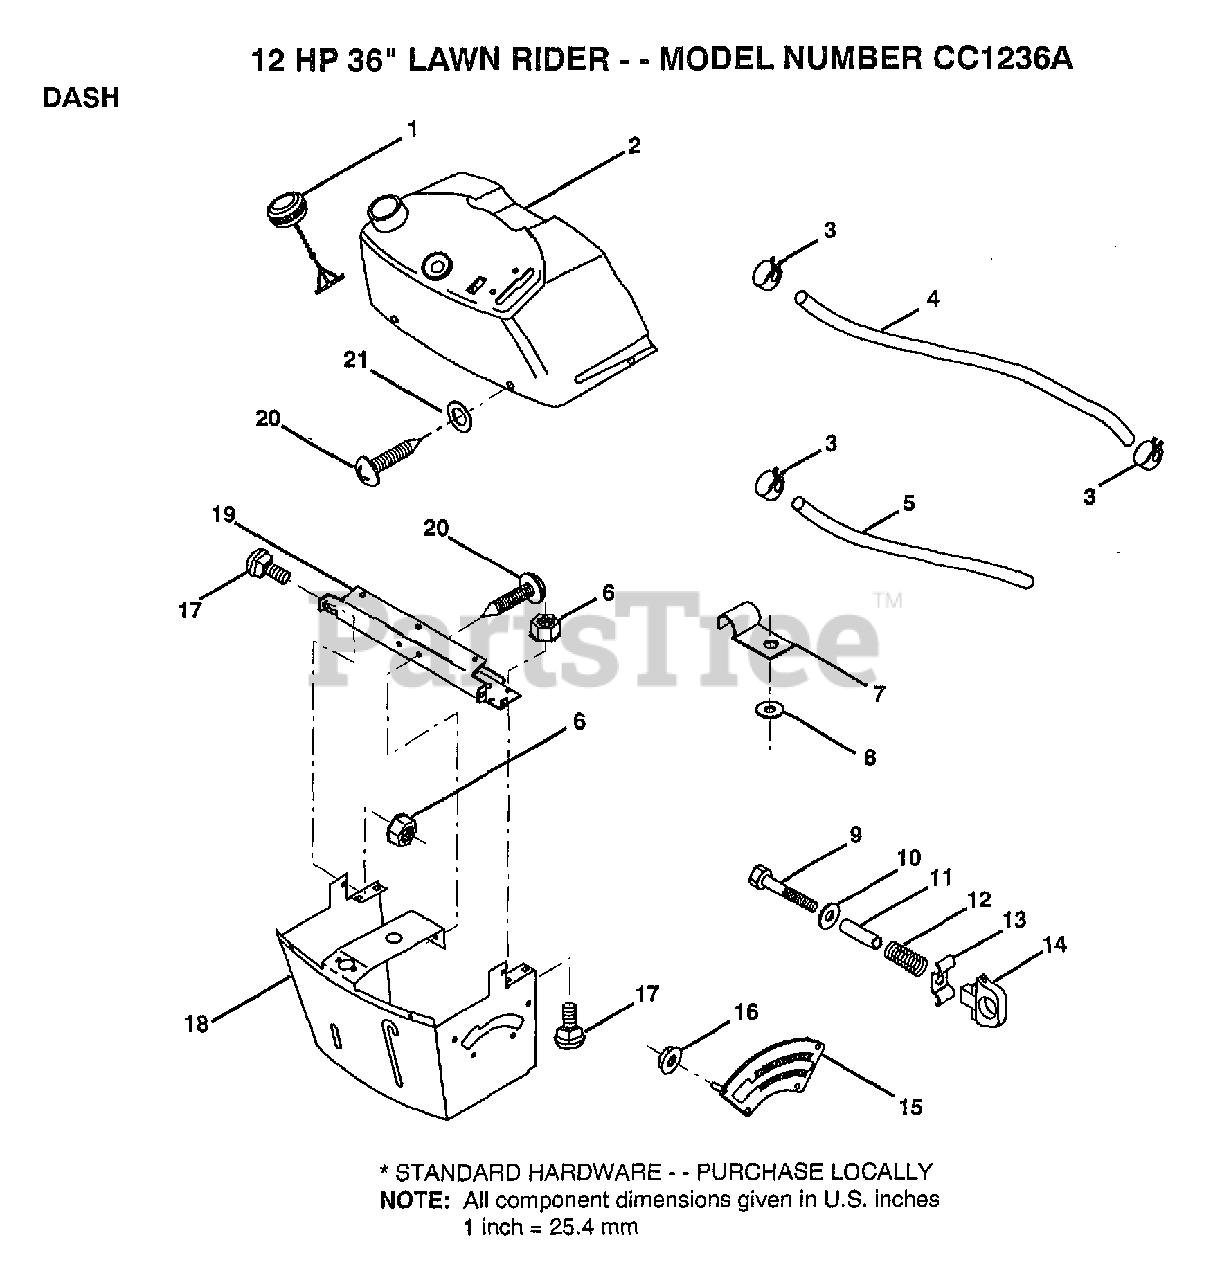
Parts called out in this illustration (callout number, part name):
3	HOSE CLAMP
5	FUEL LINE T
7	CLIP T
8	WASHER PM
9	BOLT
11	SPACER SPLIT
12	SPRING M
13	"KNOB,HGT RETAINER"
14	KNOB
15	ADJUSTER QUAD
16	NUT
17	BOLT
18	SUPT ASSY DASH
